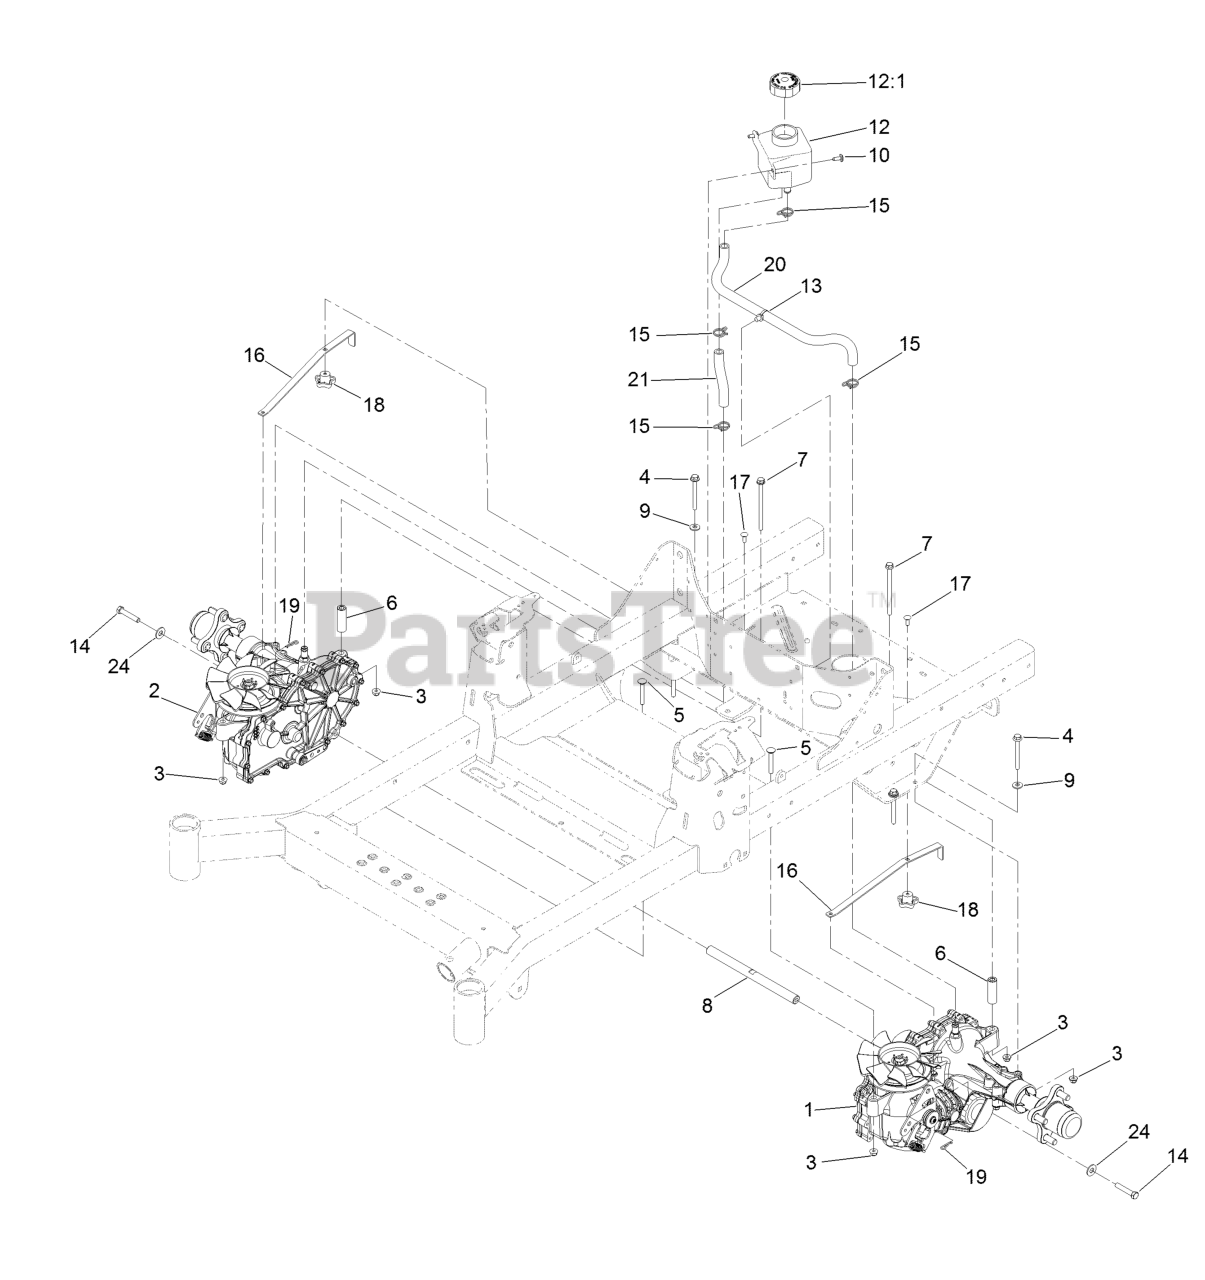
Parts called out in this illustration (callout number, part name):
1	LH Transaxle ASM
2	RH Transaxle ASM
3	Nut-HF, NI
4	Screw-HHF
5	Bolt-CARR
6	Spacer-Hydro
7	Screw HHF
8	Shaft-Spacer
9	Washer-Spring
10	Screw-Torx
12	Tank-HYD
12:1	Cap-Reservoir, HYD
13	Clip-Tie
14	Screw-HH W/Loctite
15	Clamp-Hose
16	Arm-Bypass, Hydro
17	Bolt-CARR
18	Knob-Handle
19	Pin-Cotter
20	Hose-Hydraulic
21	Hose-Hydraulic
24	Washer-Flat
